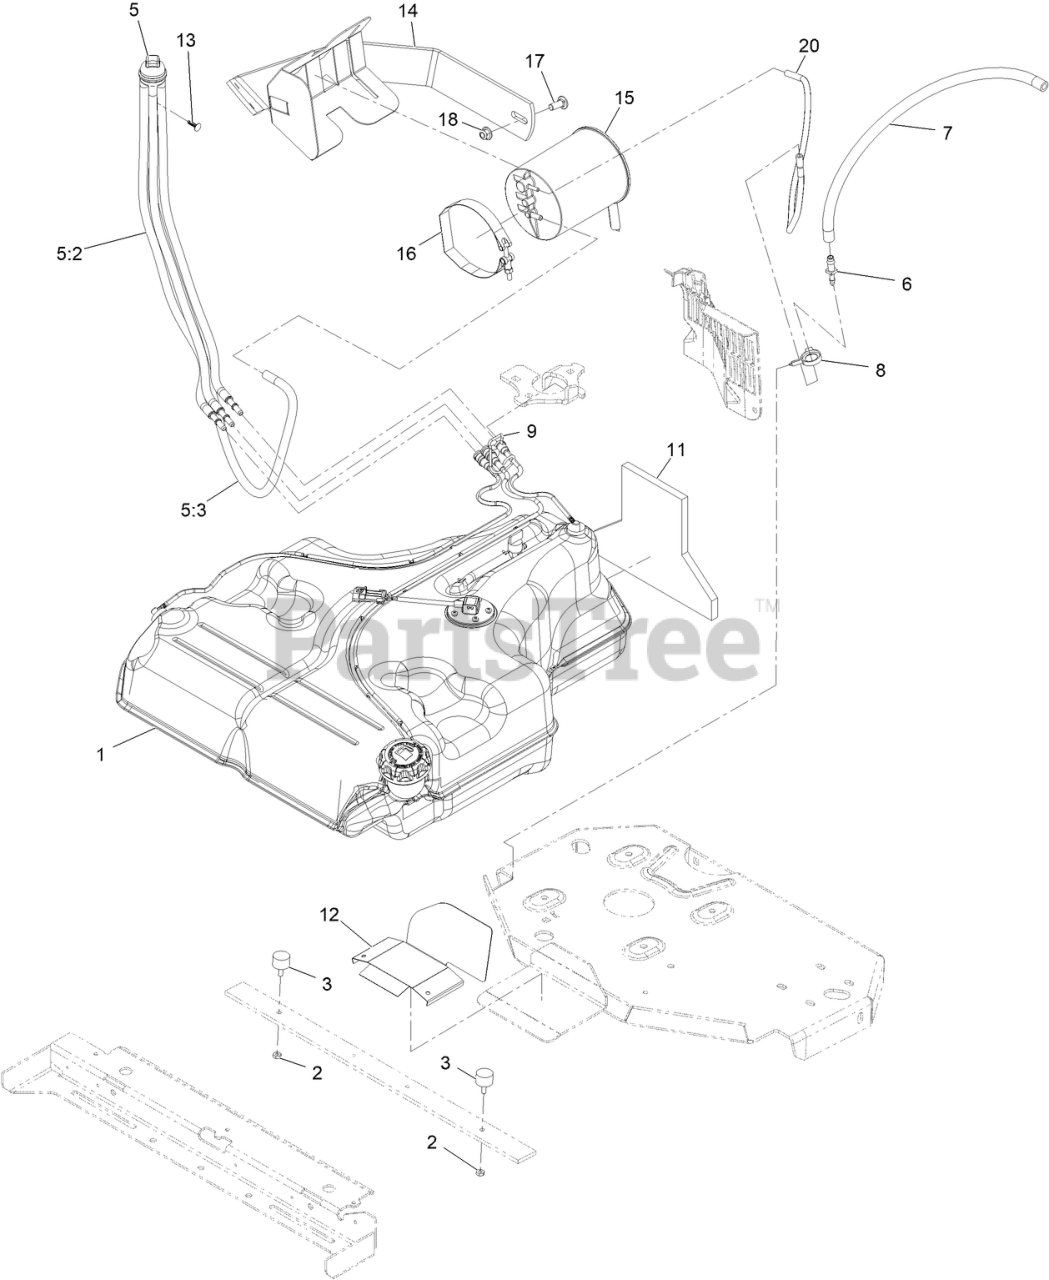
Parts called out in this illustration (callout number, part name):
1	FUEL TANK ASM
2	NUT-JAM
5	FUEL MANIFOLD VENT ASM
5:2	HOSE-FUEL
5:3	HOSE-FUEL
6	FITTING-STRAIGHT
7	HOSE-FUEL
8	CLAMP-HOSE
9	RETAINER-LINE, VAPOR
11	INSULATION-FOAM, FUEL TANK
12	GUARD-EXHAUST
13	PLUG-PLASTIC
14	MOUNT-CANISTER
15	CANISTER-CARBON, 1200CC
16	CLAMP, T-BOLT
17	SCREW-CARR
18	NUT-HF, NI
20	Hose-Vent, Formed
